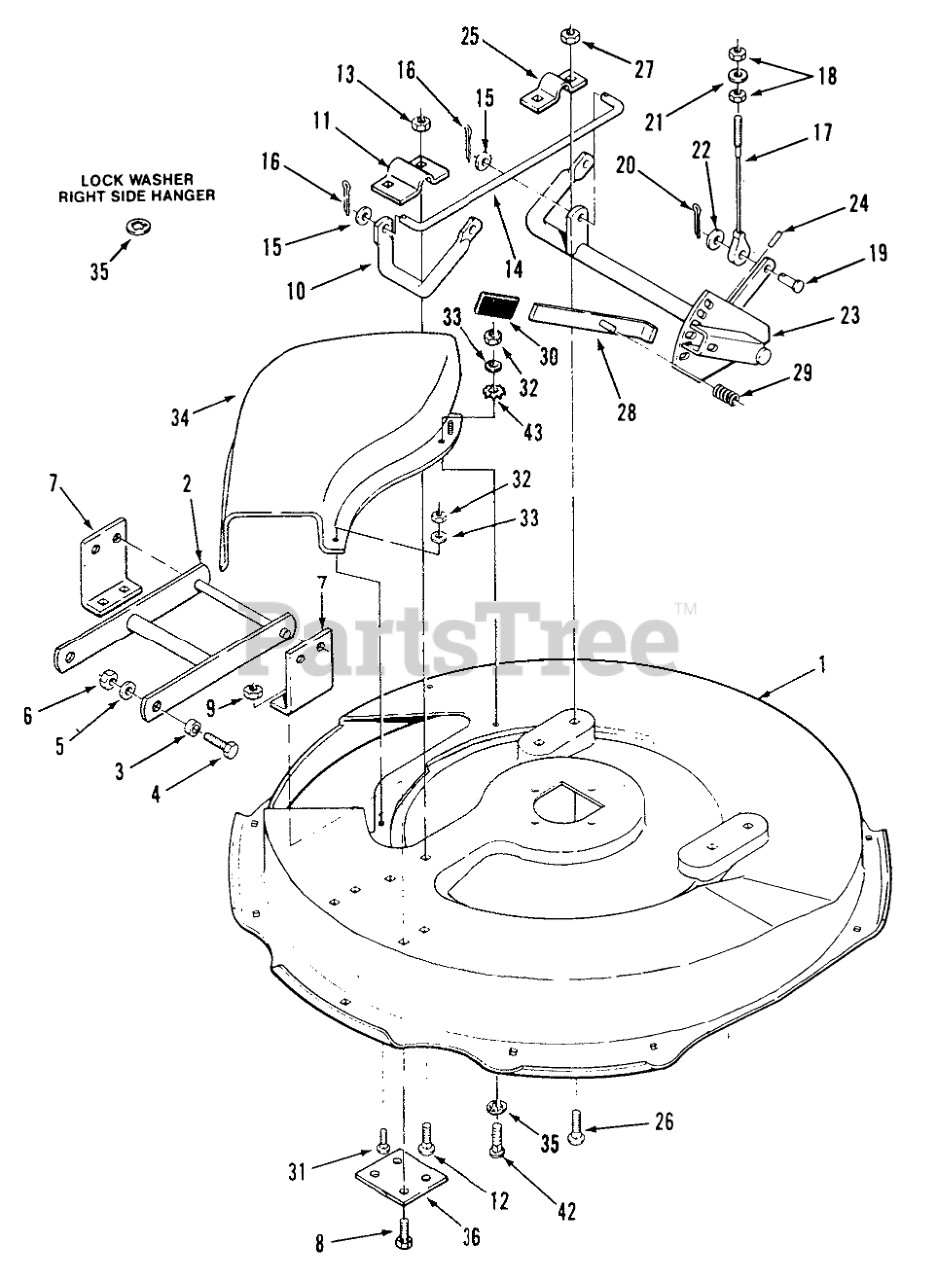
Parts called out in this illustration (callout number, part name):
1	DECK 30" MOWER R
2	ASSY MWR FRONT MO R
3	SPACER
4	BOLT
5	Washer
6	NUT
7	BRKT FRONT MOWER R
8	BOLT
9	NUT
10	ROD HEIGHT ADJ R
11	CLAMP B
12	Bolt
13	NUT
14	ROD HEIGHT ADJUST
15	Washer
16	Cotter Pin
17	CABLE MOWER SUPPORT
18	Nut
19	CLEVIS PIN
20	Cotter Pin
21	WASHER 5/16 SAE
22	Washer
23	HEIGHT ADJ ASSY R
24	SPIROL PIN
26	Bolt
27	NUT
28	LEVER ASSY
29	SPRING-COMPRESSION
31	Bolt 1/4-20 X 5/8
32	Nut
34	Deflector-Mower
35	Washer-Lock
36	PLATE-BACKUP R
42	Bolt-Carriage
43	LOCKWASHER
